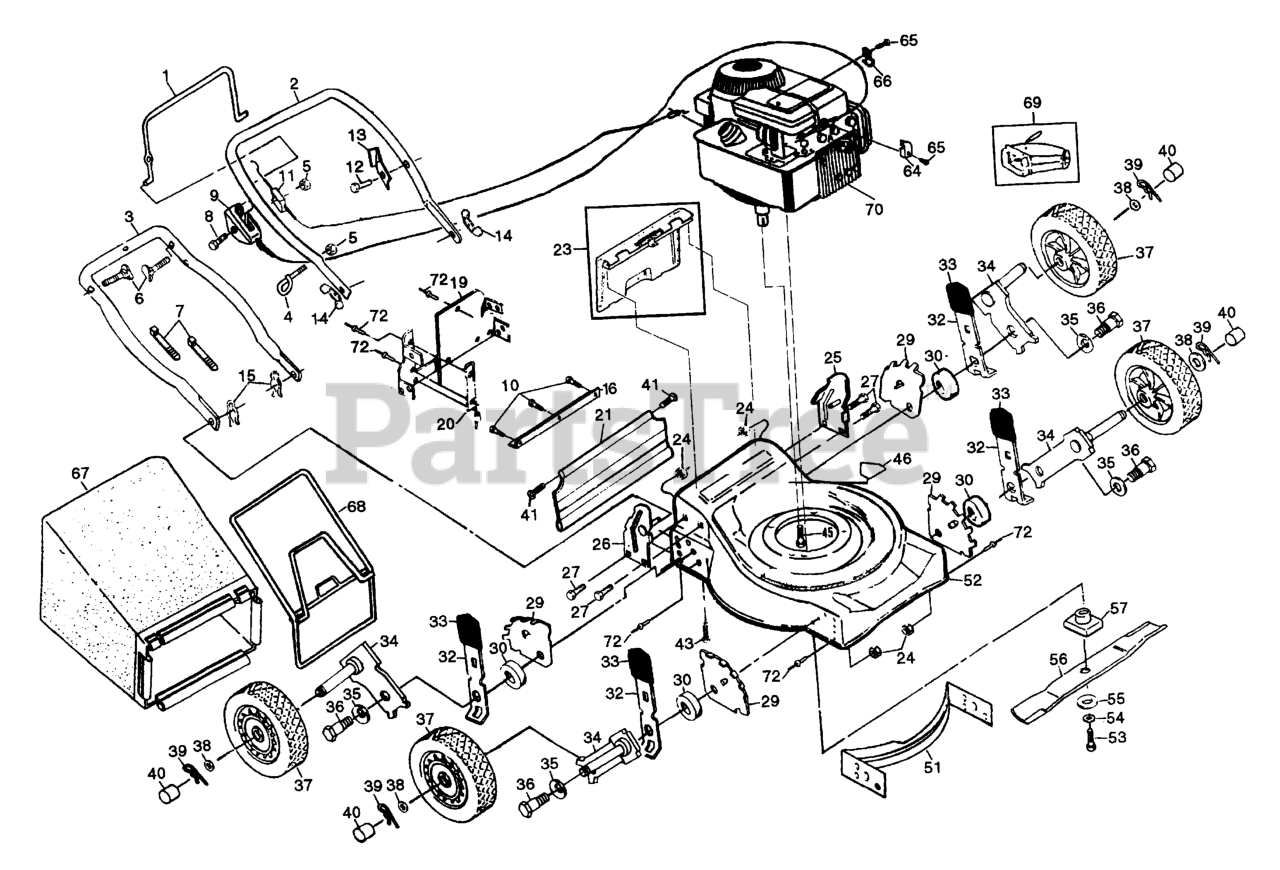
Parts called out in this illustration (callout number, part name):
1	CONTROL BAR
2	UPPER HANDLE
3	HANDLE, LOWER PM
4	ROPE GUIDE
5	NUT
6	HANDLE BOLT
7	TIE GUIDE
8	SCREW 1/4-20 X 2.12
9	THROTTLE CONTROL
11	CABLE.MZR.51.RT.SP./PU.
12	TAPPING SCREW
13	BRACKET UPSTOP
14	NUT WING PM
15	HAIRPIN COTTER
19	BACK PLATE
20	SIDE BAFFLE
21	REAR SKIRT
23	REAR DOOR ASSEMBLY KIT
24	LOCKNUT PM
25	HANDLE BRACKET LH
26	HANDLE BRACKET RH
27	SCREW
29	WHEEL ADJUST BRACKET
30	SPACER PM
32	SELECTOR SPRING
34	AXLE ARM
35	WASHER.BELLEVILLE (3 2 LB)
36	BOLT
37	Wheel & Tire Assembly 7.0 x 1-1/2
39	RETAINER CLIP PM
41	HINGE SCREW
45	BOLT
53	SCREW, HEX HD 3/8-24 X 1-3/8
54	LOCKWASHER
55	WASHER,HARDEN
56	BLADE.20.MULCH.(50DK,6020MD)
57	BLADE ADAPTOR
64	WASHER
65	SCREW.HEX.HEAD.WASHER.10-16
66	GUIDE CLIP PM
68	CATCHER.FRAME.WALK
72	RIVET BLIND
